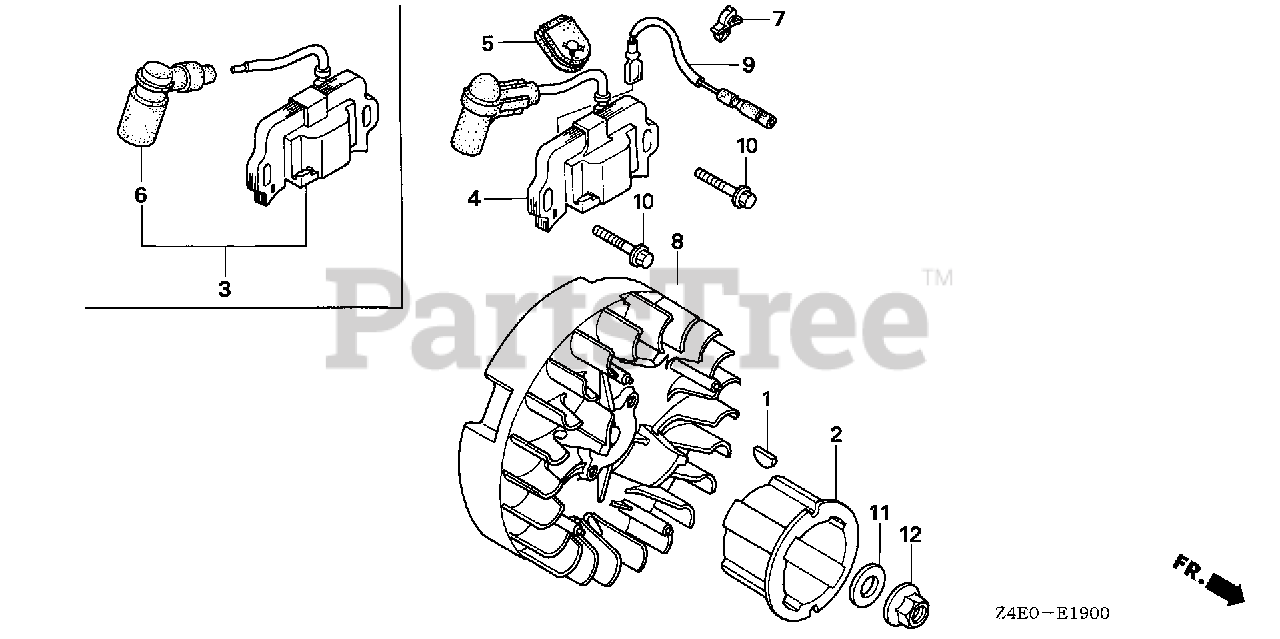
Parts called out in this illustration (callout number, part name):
1	KEY, SPECIAL
2	PULLEY, STARTER
3	COIL ASSY., IGNITION
5	GROMMET, WIRE
6	TERMINAL ASSY., IGNITION
7	CLIP, IGNITION WIRE (8MM)
9	WIRE, STOP SWITCH
10	BOLT, FLANGE (6X20) (CT200)
12	NUT, FLANGE (12MM)
